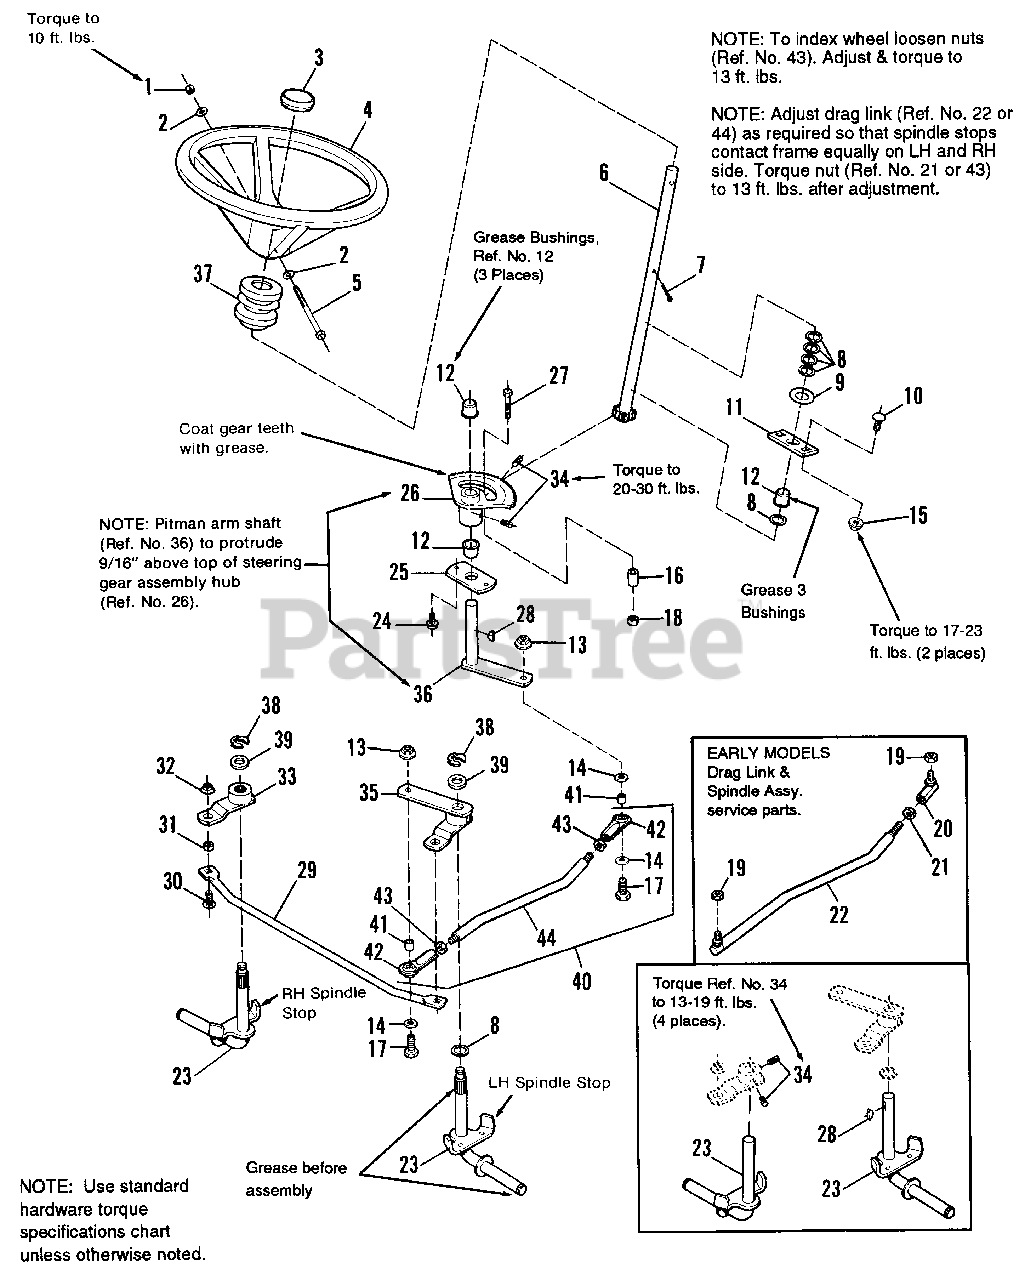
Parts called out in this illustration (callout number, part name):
1	NUT, Hex, Lock, 5/16-18
2	WASHER, Steering Wheel
3	CAP, Steering Wheel
4	STEERING WHEEL
5	CAPSCREW, 5/16-18 x 3-1/2
6	SHAFT ASSY., Steering
8	WASHER, Plain, 49/64"
9	WASHER, Plain
10	CARRIAGE BOLT, 3/8-16 x 1
11	PLATE, Mounting, Steering
12	BUSHING, Nylon
13	NUT, Hex, Flange, 3/8-16
14	WASHER
15	NUT, Hex, Flange, 3/8-16, Whizlock
16	SPACER, Stop
17	CAPSCREW, Hex Hd., 3/8-16 x 1-1/2
18	NUT, Hex, Lock ESNA, Light, 5/16-18
19	NUT, Special, 3/8-24
20	BALL JOINT (Round)
21	NUT, Jam, 3/8-24
22	DRAG LINK (service with Drag Link Assy., Ref. No. 40)
23	SPINDLE ASSY., Keyed
23	SPINDLE ASSY., Splined
24	SCREW, Taptite, 5/16-18 x 1
25	SECTOR MOUNTING PLATE
26	GEAR ASSY., Steering
27	CAPSCREW, Hex, 5/16-18 x 1-1/4
28	KEY, Hi Pro (Qty. 3 on Early Models. See inset page 4.)
30	CARRIAGE BOLT, 3/8-16 x 1
32	NUT, Hex, Lock, Flange, 3/8-16
33	ARM ASSY., Steering, R.H., Keyed
33	ARM ASSY., Steering, R.H., Splined
34	SETSCREW, Sq. Hd., 5/16-18 x 1/2 (Qty. 6 on Early Models. See inset page 4.)
35	STEERING ARM ASSY., L.H., Keyed
35	STEERING ARM ASSY., L.H., Splined
36	PITMAN ARM ASSY.
37	TUBE, Steering
38	KLIP RING, 5/8
39	WASHER
40	DRAG LINK ASSY. (Includes Ref. Nos. 13, 14, 17, 41-44)
42	BALL JOINT (Flat)
43	NUT, Hex, Jam, 1/2-20
